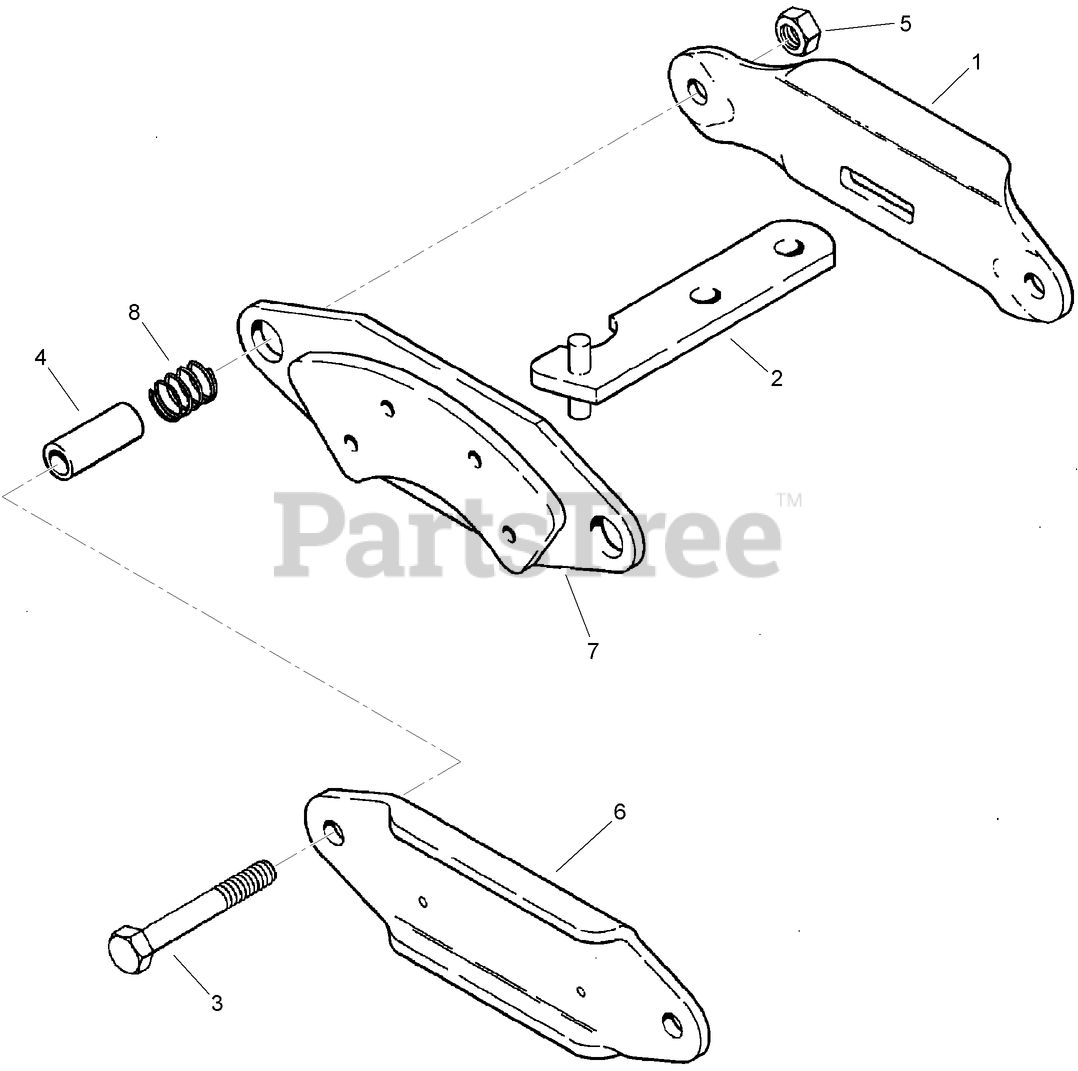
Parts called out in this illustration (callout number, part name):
1	BRACKET
3	SCREW-CAP
4	SPACER-TUBE
6	OUTSIDE HOLDER AND PAD ASM
7	INSIDE HOLDER AND PAD ASM
